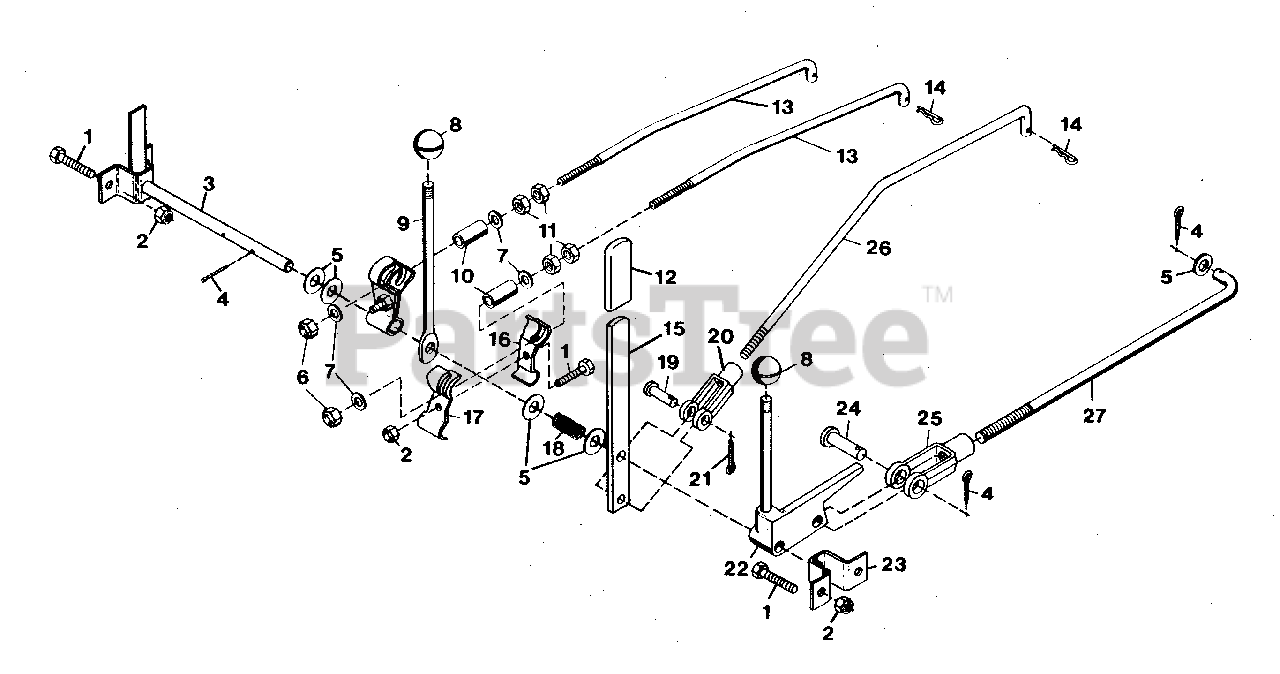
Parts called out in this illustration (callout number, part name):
1	BOLT, HEX 5/16-18X.75
2	WELDMENT, CROSS SHAFT
3	KNOB, CONTROL
4	LEVER, SHIFT
5	WASHER, FLAT .531X1.06X.095
6	NUT, LOCK 5/16-18
7	PIN, COTTER .12X1.0
8	WASHER, FLAT .438X1.00X.083
9	NUT, LOCK 3/8-16
10	ROD, SHIFT
11	NUT, JAM 3/8-16
12	BUSHING, .400X.500X1.65
13	ARM, SHIFTER R.H.
14	ARM, SHIFTER L.H.
15	SPRING, COMPRESSION
16	PIN, COTTER HAIR
17	ROD, 2-SPEED
18	GRIP, HANDLE
19	CLEVIS, 3/8-24 ADJUSTABLE
20	PIN, CLEVIS .375X.948
21	PIN, COTTER .09X.75
22	LEVER, HI-LO SHIFT
23	ASSEMBLY, PTO CONTROL
24	ROD, PTO
25	YOKE, 1/2-20 ADJUSTABLE
26	PIN, CLEVIS .500X1.213
27	BRACKET, CROSS SHAFT
